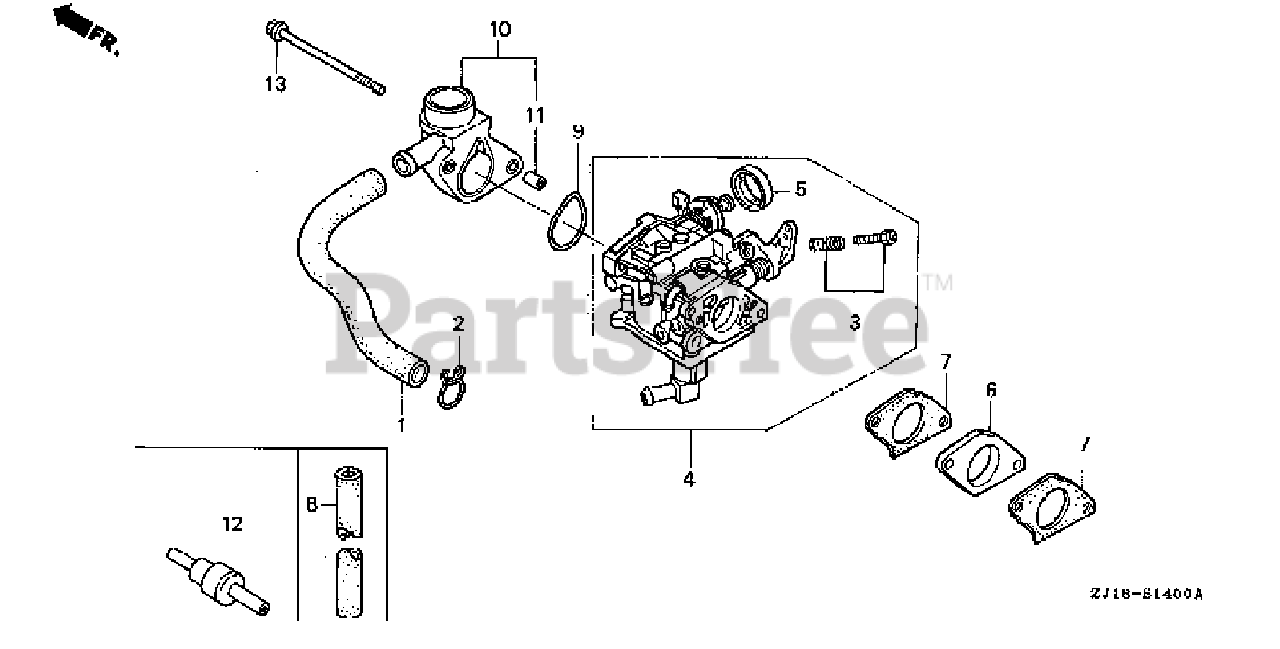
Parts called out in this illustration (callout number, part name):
1	TUBE, BREATHER
2	CLIP, BREATHER TUBE
3	SCREW SET
4	CARBURETOR ASSY. (BGL1A A)
5	CAP, CHOKE LEVER DUST
6	INSULATOR, CARBURETOR
7	GASKET, CARBURETOR
8	RUBBER, SUPPORTER
9	GASKET, AIR CLEANER
10	ELBOW, AIR CLEANER
11	COLLAR, DISTANCE
12	VALVE, DASHPOT CHECK
13	BOLT, FLANGE (6X105)
